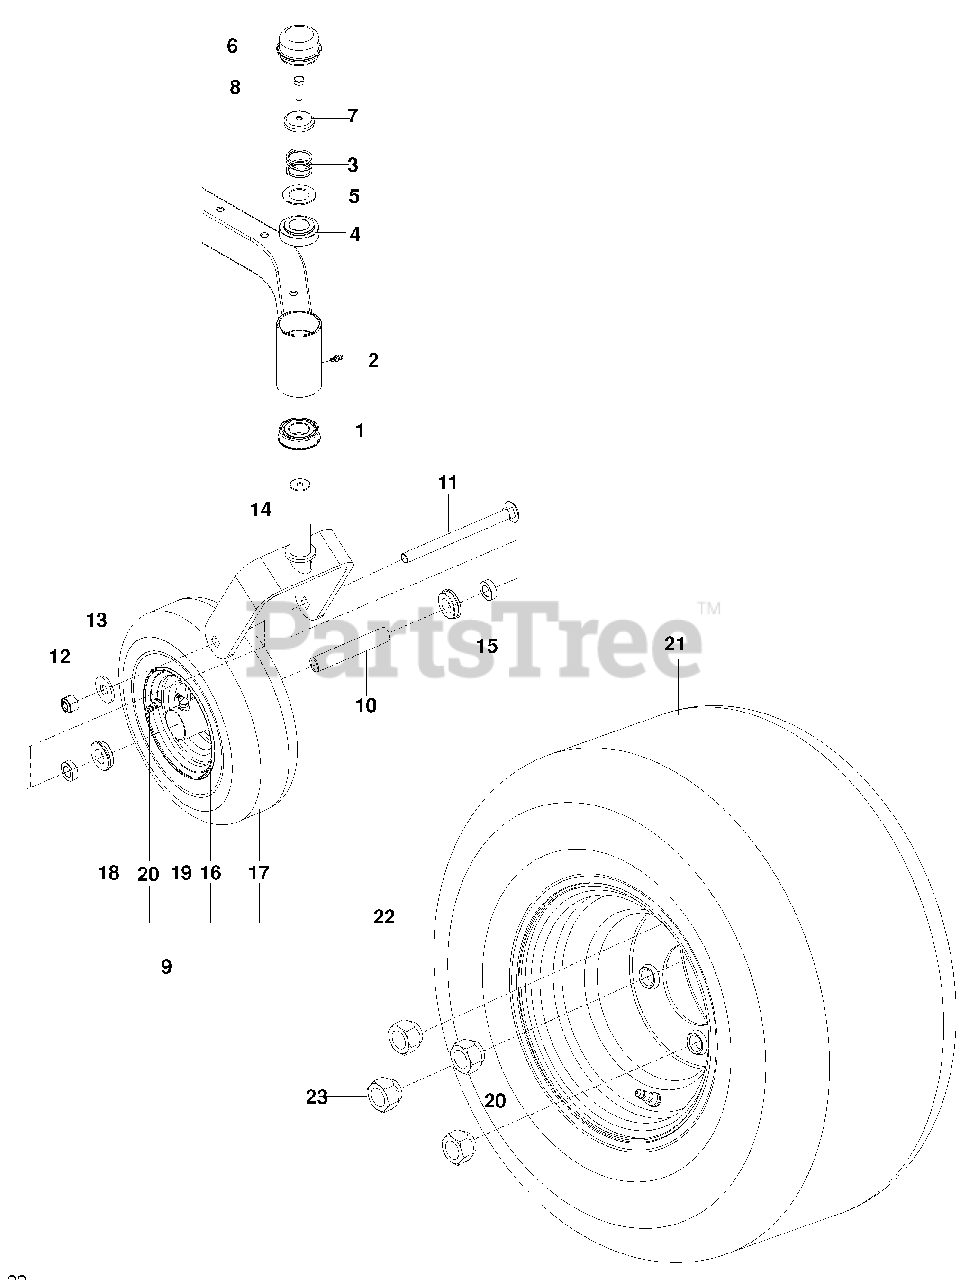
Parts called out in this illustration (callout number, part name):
1	BEARING, FLANGED
2	ZERK 3/16 DRIVE
3	SPRING, CASTER
4	BUSHING, CASTER
6	GREASE CAP
7	PLUG, CASTER
8	HHB 5/16-18 x 1 NYLOC
9	CASTER TIRE ASSY
11	RHSNB 1/2-13 x 6 1/2
12	NUT 1/2-13 HEX NYLOC
13	WASHER 1/2 FLT
14	YOKE
15	SPACER 5/16
17	CASTER TIRE, 410/350 4 PLY
18	BEARING, FLANGED
19	ZERK
20	VALVE STEM
21	TIRE ASSY, REAR 18 x 8.5 965921501, 966495701
22	RIM, 8 x 7 965921501, 966495701
23	NUT, LUG 1/2-20 HEX
